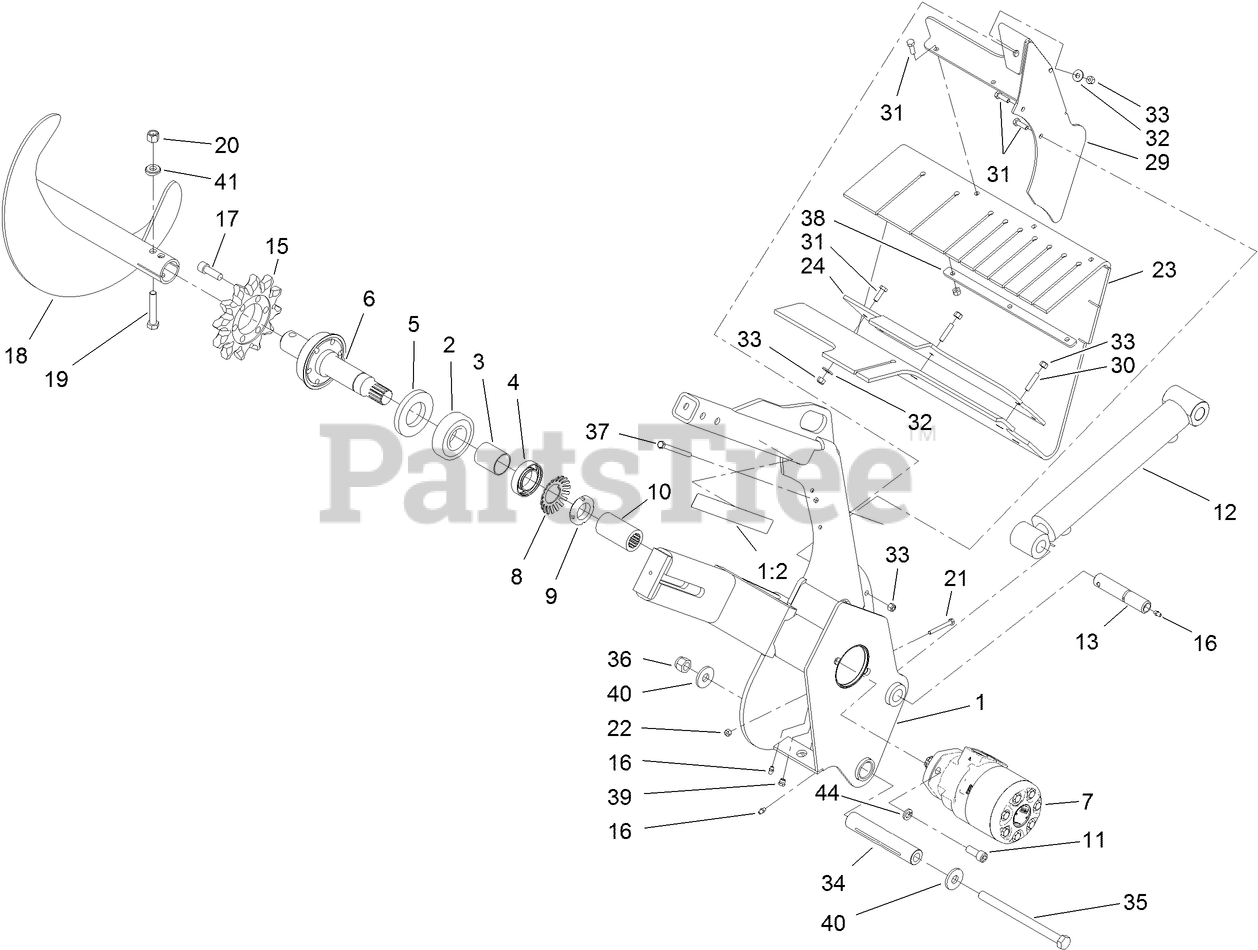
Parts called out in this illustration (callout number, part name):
1	TRENCHER HEAD ASM
1:2	DECAL-DANGER
2	BEARING-BALL
3	SPACER
4	BEARING-BALL
5	SEAL-GREASE
6	SHAFT-TRENCHER
7	HYD MOTOR ASM
8	LOCKWASHER-BEARING
9	LOCKNUT-BEARING
10	COLLAR-SPLINED
11	SCREW-HSH
12	HYD CYLINDER ASM
13	PIN-PIVOT
15	SPROCKET-TRENCHER
16	FITTING-GREASE
17	SCREW-HSH
18	AUGER-TRENCHER
19	SCREW-HH
20	NUT-LOCK, NI
21	SCREW-HH
22	NUT-LOCK, NI
23	SHIELD-DIRT
24	BAR-CLAMP
29	BRACKET-SHIELD
30	SCREW-HSH
31	SCREW-HH
32	WASHER-FLAT
33	NUT-LOCK, NI
34	SPACER-PIVOT
35	BOLT-HH
36	NUT-LOCK, NI
37	SCREW-HH
38	PLATE-STRAP, SHIELD
39	FITTING-LUBE
40	WASHER-HARDENED
41	WASHER-SADDLE
44	WASHER-LOCK
